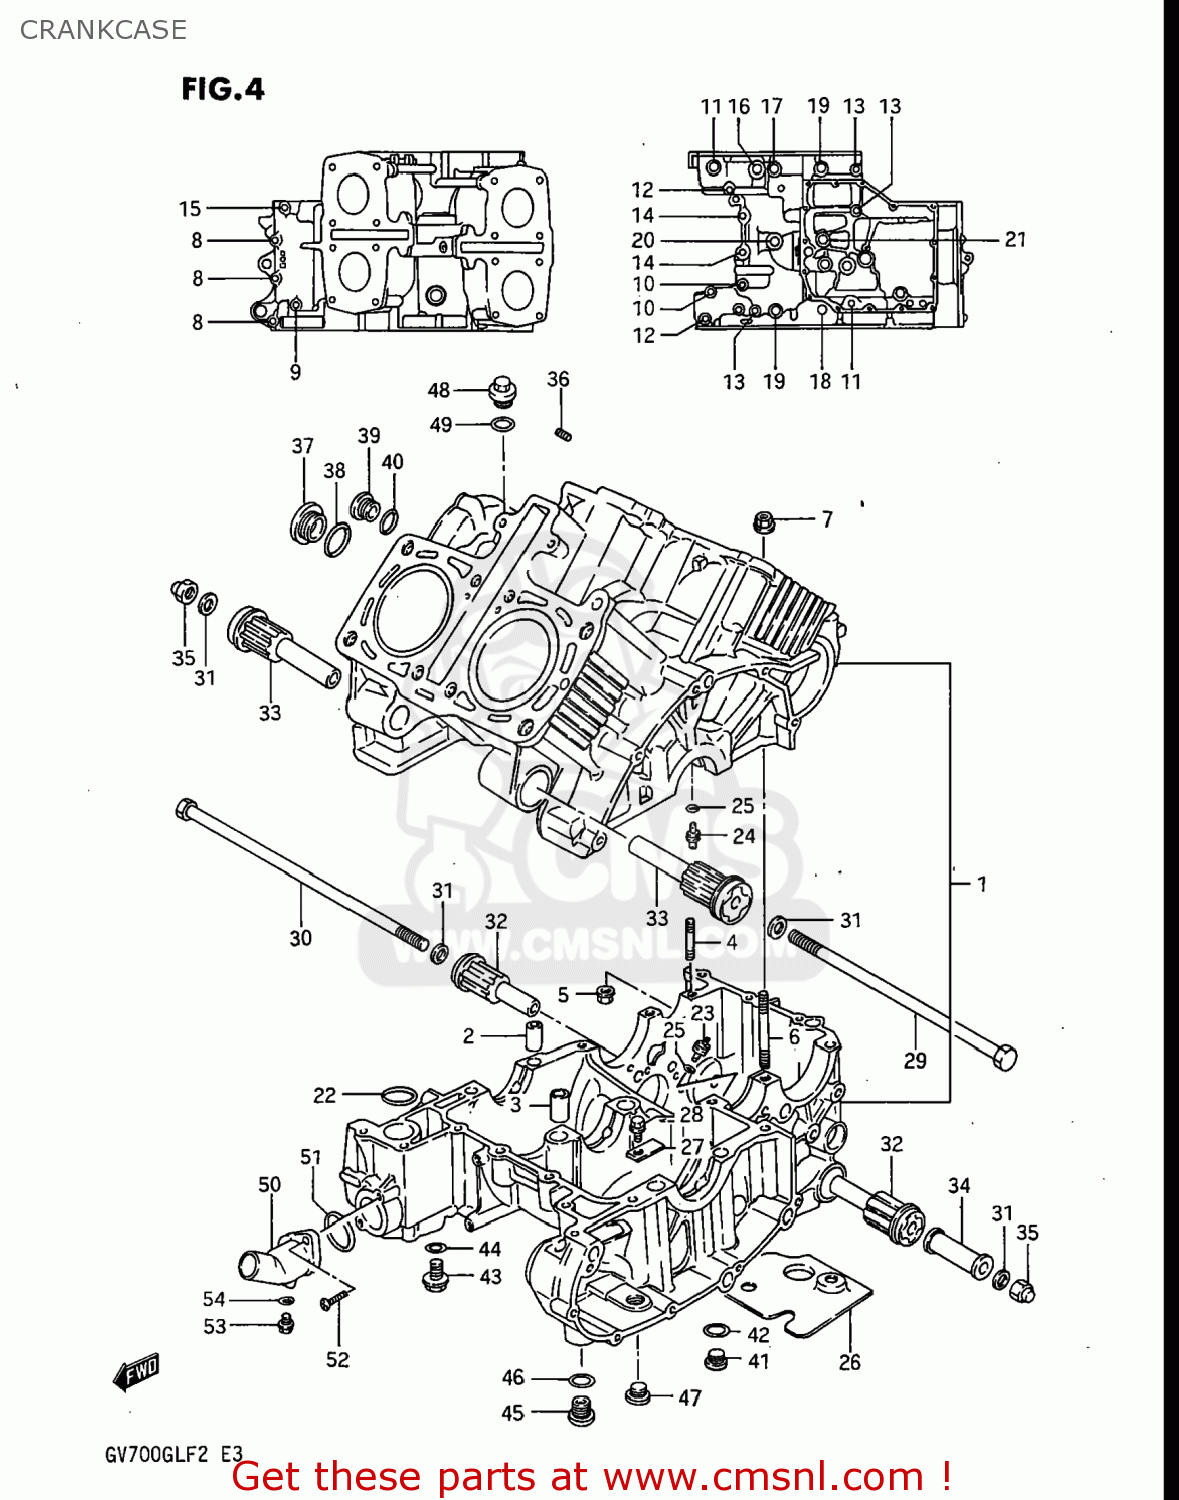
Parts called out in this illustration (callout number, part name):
1	CRANKCASE SET
2	PIN(10.4X13X22)
3	PIN
4	STUD 6X50
5	NUT
6	STUD BOLT
7	NUT 8MM
8	BOLT 6X35
9	BOLT
10	BOLT (6X90)
11	BOLT
12	BOLT(6X100)
13	BOLT
14	BOLT
15	BOLT 8X60
16	BOLT 8X35
17	BOLT L:140
18	BOLT(10X150)
19	BOLT
20	BOLT
21	BOLT
22	O-RING (D:3 ID:27)
23	JET,OIL GALLERY
24	JET,OIL GALLERY(18)
25	O RING(D:1.2,ID:4)
26	PLATE,OIL SEPARATOR
27	MAGNET, DUST CATCH
28	BOLT
29	BOLT
30	BOLT 10X305
31	WASHER
32	BUSHING,ENGINE MOUNTING,REAR
33	BUSHING,ENGINE MOUNT
34	SPACER,ENGINE MOUNT(L:65)
35	NUT
36	PLUG
37	PLUG
38	O-RING
39	PLUG
40	O RING(D:3.1,ID:16.8)
41	PLUG
42	GASKET(16X22X2) (NAS)
43	BOLT
44	GASKET(10.1X16X1) (NAS)
45	PLUG
46	GASKET(14X19.2X2) (NAS)
47	PLUG
48	PLUG
49	O RING(D:3.1,ID:16.8)
50	CONNECTOR,WATER INLET
51	O RING(D:2.4,ID:31.7)
52	SCREW
53	BOLT,DRAIN
54	GASKET 8.2X14X1 (NAS)
